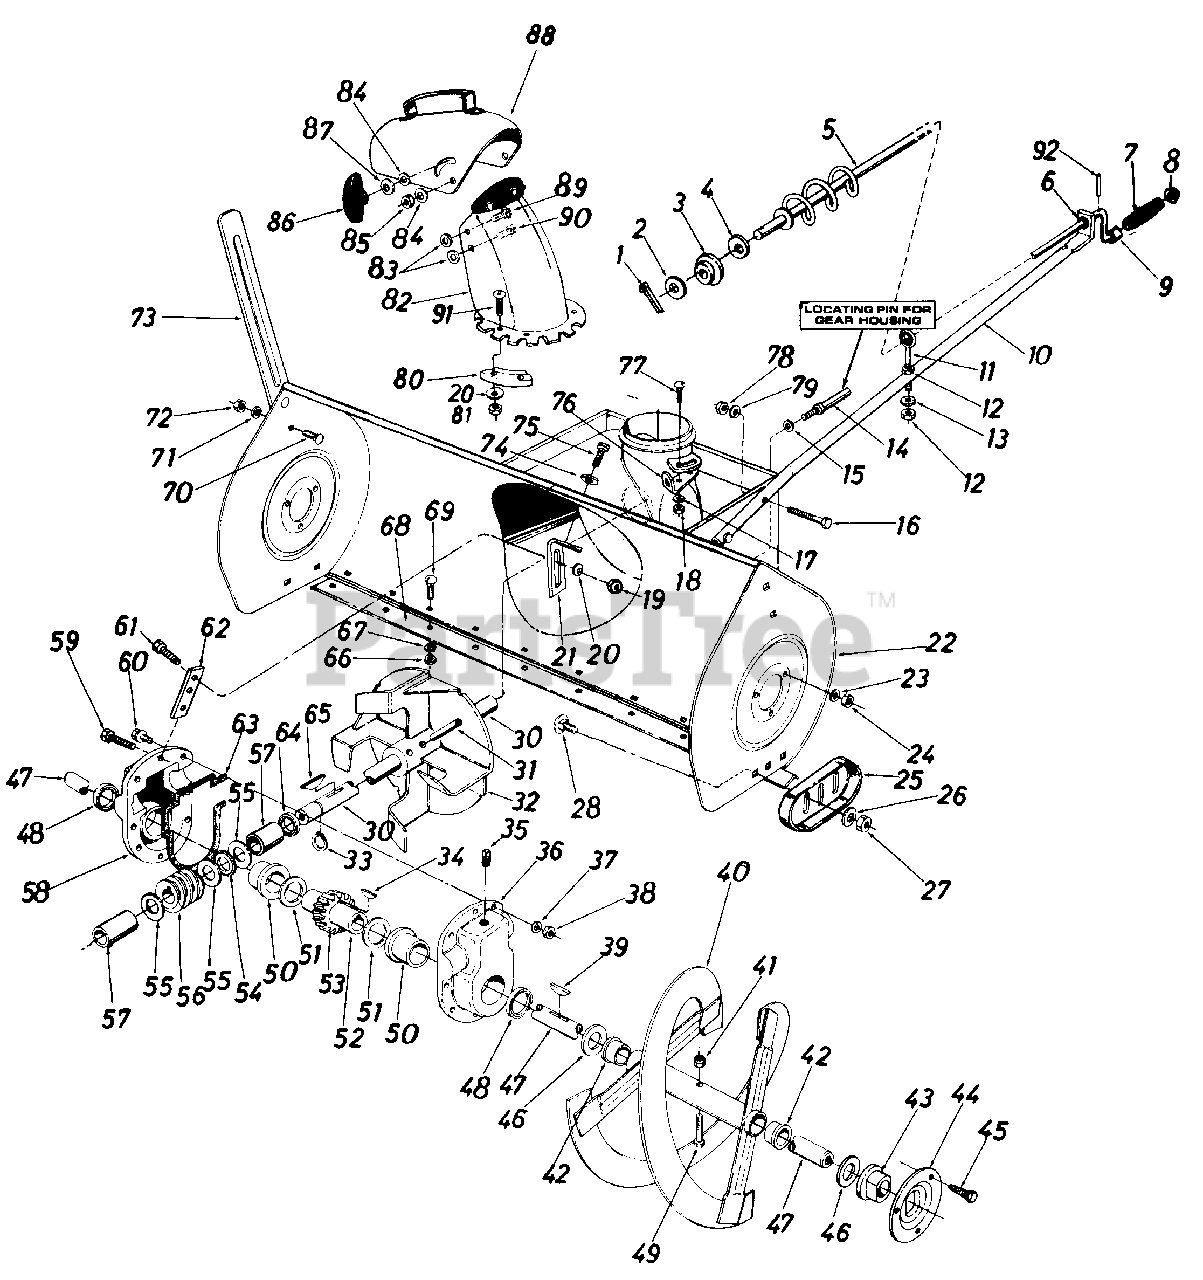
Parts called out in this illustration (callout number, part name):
1	Cotter Pin
2	Fl.-Wash. .39" I.D. x .62" O.D.
3	Plastic Bushing
4	Fl.-Wash. .385 ' I.D. x .62" O.D.
5	Chute Crank Ass'y.
6	Plastic Bushing
7	Knob Ball 3/8 Dia. Hole
8	Push Nut 3/8" Rod
9	Spacer .385 I.-D. x .50" I.D.
10	Chute Crank Support Tubing
11	Eyebolt
12	Hex Nut 5/16-18 Thd.*
13	Bell.-Wash. 345" I.D. x .88" O.D.
14	Stud 3/-8-16 x 2.75" Lg.
15	Bell.-Wash. .400" I.D. x .88" O.D.
16	Hex Bolt 3/8-24 x 1.25" Lg.*
17	Bell.-Wash. .345" I.D. x .88" O.D.
18	Hex Nut 5/16-18 Thd.*
19	Hex Nut 1/428 Thd.
20	Bell.-Wash. .265" I.D. x .75"O.D.
22	45" Snow Blower Housing Ass'y
23	L.-Wash. 5/16" I.D.*
24	Hex Nut 5/16-18 Thd.*
25	Slide Shoe
26	Bell.-Wash. .400" I.D. x .88" O.D.
27	Hex Jam Nut 3/8-16 Thd.
28	CarriageBolt 3/8-16 x .62" Lg.*
30	Blower Axle .875" Dia. x 14.75 4
31	SpringPinSpir. 5/16" Dia. x 1.75' 4
32	Blower Fan Ass'y.
33	Snap Ring For .875U Dia. Shaft
34	#91 Woodr-Key 1/4 x 3/4" Dia. (HDN)
35	Vent Plug
36	Comp. Gear Hsg. Half-L.H.
37	Spr.-Wash. .32" I.D. x .62" O.D
38	Hex Ins. L.-Nut 5/16-18 Thd.
39	#91 Woodr-Key 1/4 x 3/4" Dia. (HDN)
41	Hex Ins. L.-Nut 5/16-18 Thd.
42	Plastic Bushing
43	Flange Brg. w/flats 1" I.D.
44	Bearing Housing
45	Hex Sems Bolt 5/16-18 x .75" Lg.*
46	Fl Wash 1.00" x 1.75" O.DI.
47	Spiral Axle
48	Flange Bearing 1.503" I.D.
49	Shear Bolt 5/16-18 x 1.75" Lg.
50	Oil Seal 1.50" I.D.
51	Fl.-Wash. 1.50" I.D. x 2.00" O.D.
52	Worm GearShaft
53	Double Threaded Worm Gear -L.H.
54	Thrust Brg. - .88" I.D. x 1.44"O.D.
55	Fl.-Wash..88" I.D. x 1.4"0.D.
56	Double Threaded Worm - L.H.
57	Sleeve
58	1 Complete Gear Hsg. Half - R.H.
59	Hex Bolt 5/16-18xl.25" Lg.*
60	Hex Bolt 5/16-18 x 1.0" Lg. (Grade 5)
61	Hex Bolt 1/4-28 x .75" Lg.
62	Gear HousingSupport Plate
63	Rubber Gasket
64	Oil Seal - .875" I.D.
65	#9 Hi-Pro Key 3/16 x 3/4" Dia. (HT.)
66	Hex Nut 5/16-18 Thd.*
67	L.-Wash. 5/16" I.D.*
69	Carriage Bolt 5/16-18 x 1.00" Lg.*
70	Carriage Bolt 5/16-18 x .62" Lg.*
71	L.-Wash.5/16" I.D.*
72	Hex Nut 5/16-18 Thd.*
73	Guide Blade
74	Bell.-Wash. .345" I.D. x .88" O.D.
75	Hex Wash. Hd. AB Tap Scr. 5/16 x .75" Lg.
77	Carriage Bolt 5/16-18 x .75" Lg.*
78	Hex Ins. L.-Nut 3/8-24 Thd.
79	L.-Wash. 3/8" I.D.4
80	Chute Flange Keeper
81	Hex Cent. L.-Nut 1/4-2 Thd.
82	Chute Ass'y. w/ChuteGuard
83	Fl.-Wash. .285" I.D. x 1.25" O.D.
84	Bell.-Wash. .345" I.D. x .88" O.D.
85	HexCent. L.-Nut5/16-18 Thd.
86	Knob Handle
87	Bell.-Wash. .345" I.D. x .88" O.D.
88	Top Chute Ass'y.
89	Carriage Bolt 5/16-18 x 1.00" Lg.*
90	Carriage Bolt 5/16-18 x .62" Lg 4
91	Truss Mach. Scr. 1/4-20 x .50"
92	Fl.-Wash. .285" I.D. x 1.25" O.D.
